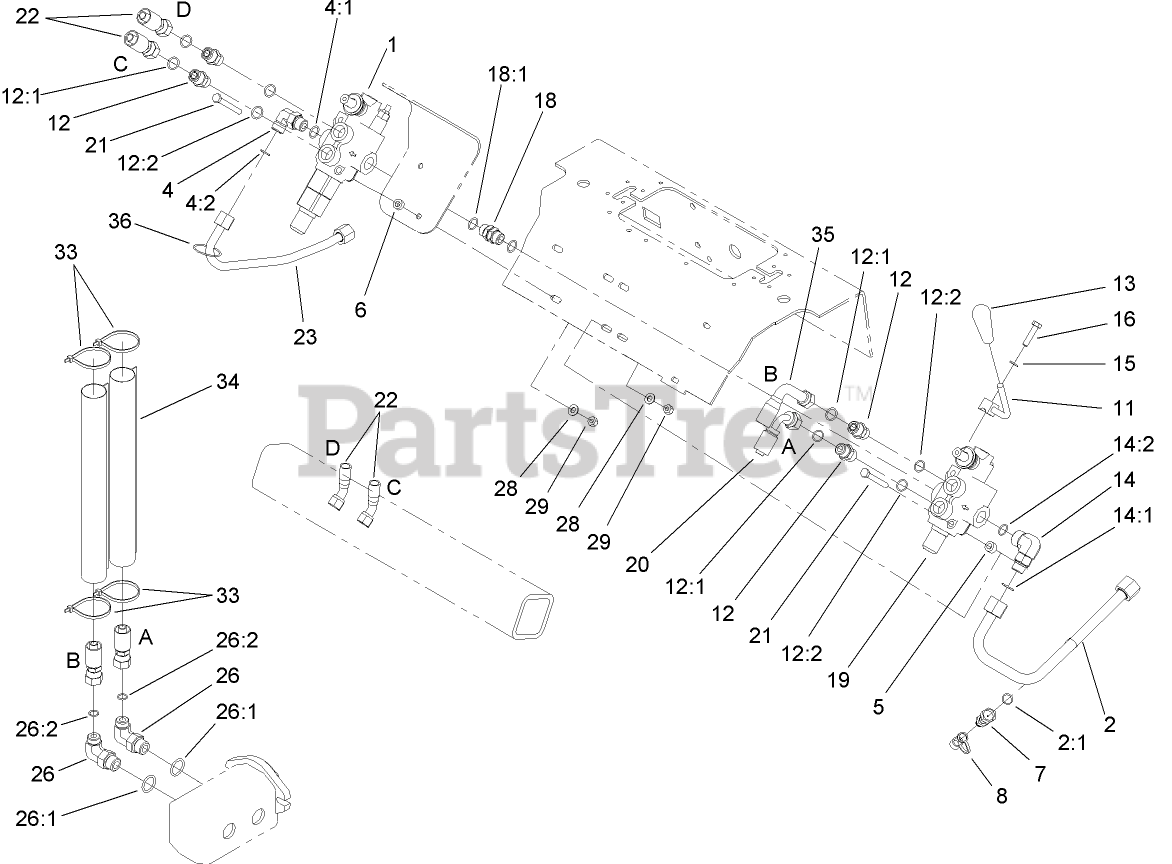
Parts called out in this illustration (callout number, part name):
1	VALVE-HYD, AUXILIARY
2	HYD TUBE ASM
2:1	O-RING
4	FITTING-ELBOW-90 DEG
4:1	O-RING
4:2	O-RING
5	SPACER
6	SPACER
7	NIPPLE-TEST
8	CAP-DUST
11	LEVER-CONTROL
12	FITTING-STRAIGHT
12:1	O-RING
12:2	O-RING
13	KNOB-TAPERED
14	Fitting-Elbow, 90 DEG
14:1	O-RING
14:2	O-RING
15	WASHER-LOCK
16	SCREW-HH
18	FITTING-THREAD, STRAIGHT
18:1	O-RING
19	VALVE-SELECTOR, HYD
20	HOSE-HYD
21	SCREW-HH
22	HOSE-HYD
23	TUBE-HYD
26	FITTING-ELBOW 90
26:1	O-RING
26:2	O-RING
28	WASHER-PLAIN
29	NUT-LOCK, NI
33	TIE-CABLE
34	SLEEVE-THERMAL
35	HOSE-HYD
36	TIE-CABLE
